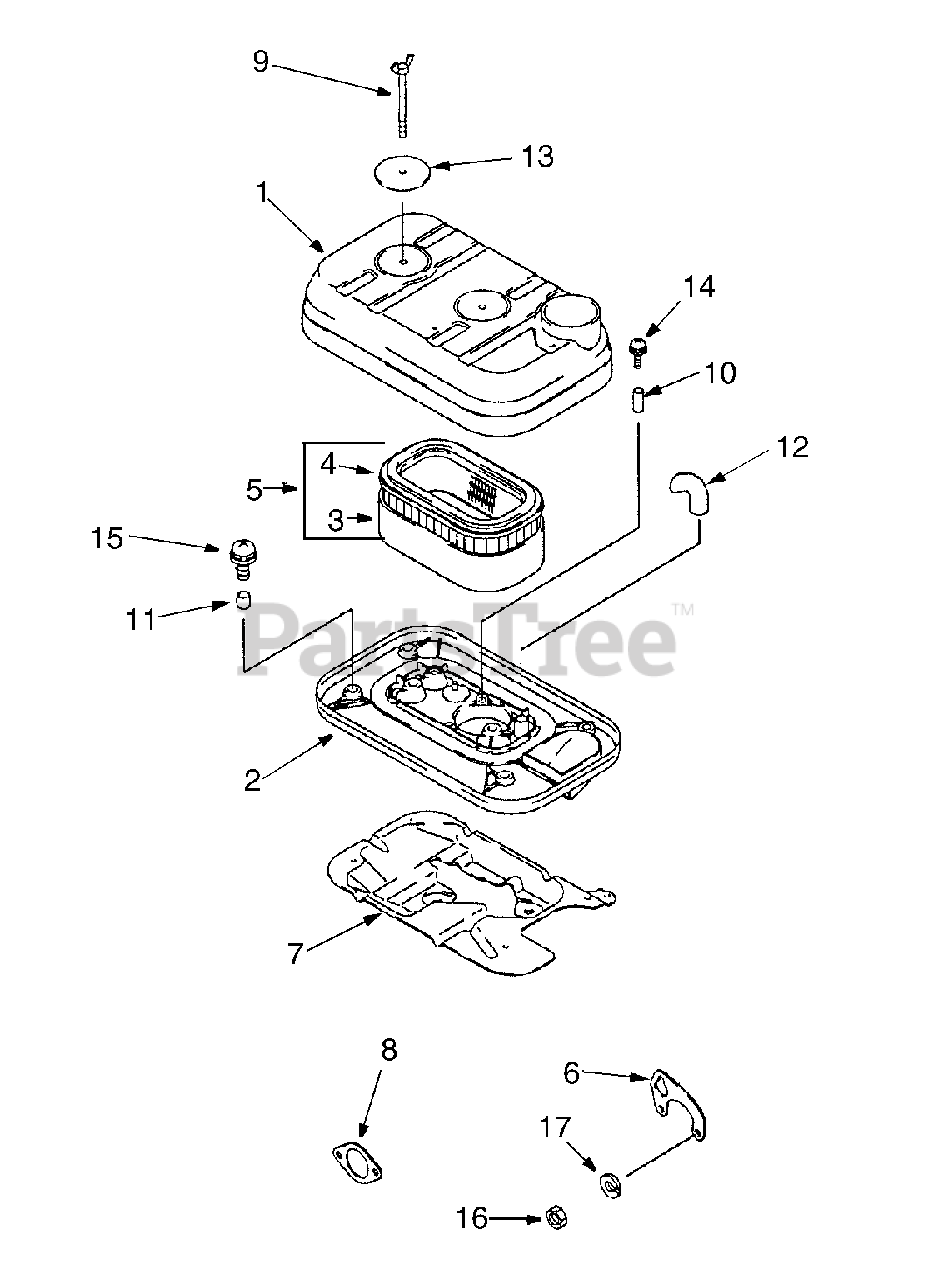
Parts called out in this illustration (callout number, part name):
1	Case, Air Filter
2	Base, Air Filter
3	Element, Foam
4	Element, Air Filter
5	Air Filter Ass'y.
7	Bracket, Air Filter
8	Gasket, Muffler
10	Collar, 5.1 x 6.3 x 14
11	Collar, 6.2 x 7.8 x 7.5
14	Screw, Pan, WSP
16	Nut, Hex
17	Washer, Spring
